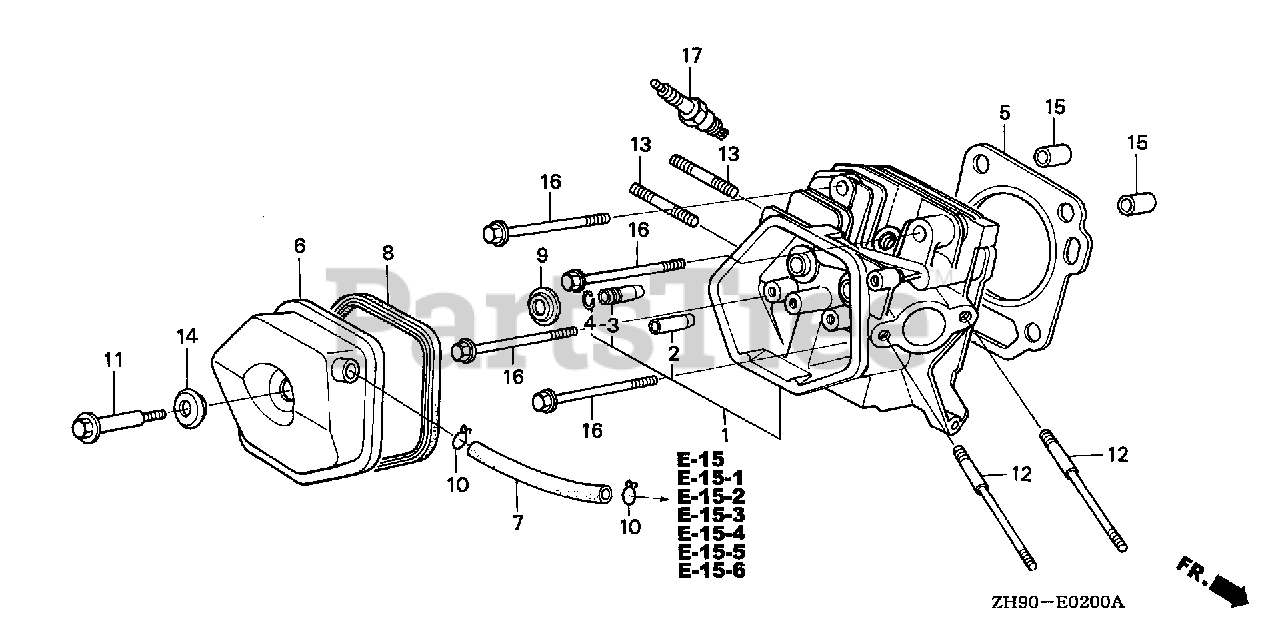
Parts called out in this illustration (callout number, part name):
1	CYLINDER HEAD
2	GUIDE, VALVE (OVER SIZE)
3	GUIDE, EX. VALVE (OVER SIZE)
4	CLIP, VALVE GUIDE
5	GASKET, CYLINDER HEAD
6	COVER, HEAD
7	BULK HOSE, VACUUM (11X1000) (11X100)
8	GASKET, HEAD COVER
9	SEAT, VALVE SPRING
11	BOLT, HEAD COVER
12	BOLT, STUD (8X123)
13	BOLT, STUD (8X47)
13	BOLT, STUD (8X32)
14	WASHER, HEAD COVER
15	PIN, DOWEL (12X20)
16	BOLT, FLANGE (10X80)
17	SPARK PLUG (BPR5ES) (NGK)
17	SPARK PLUG (W16EPR-U) (DENSO)
17	SPARK PLUG (BPR6ES) (NGK)
17	SPARK PLUG (W20EPR-U) (DENSO)
